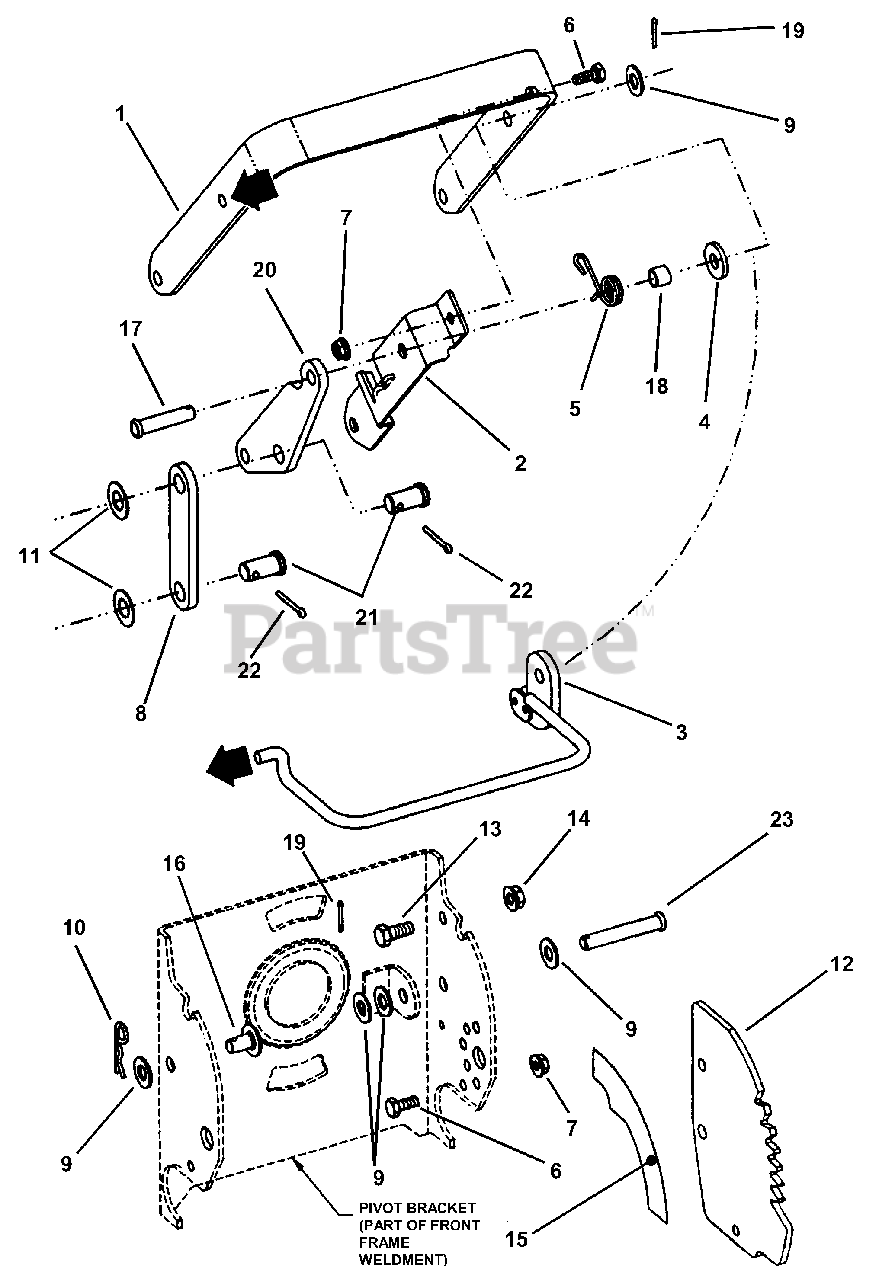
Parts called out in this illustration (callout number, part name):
1	HANDLE, Deck Lift
2	BRACKET, Pivot Support
3	WELDMENT, Deck Lift Handle
4	WASHER, Slipper
5	SPRING, Torsion (Deck Position)
6	SCREW, 1/4-20 x 5/8" Hex Head Cap, Grade 5
7	NUT, 1/4-20 Hex Flange Lock
8	LINK, Connector
9	WASHER, 3/8" Flat
10	HAIRPIN, 3/32 x 1-1/2"
11	WASHER, 1/2" SAE Flat
12	DETENT, Lift Handle
13	SCREW, 5/16-18 x 3/4" Hex Cap, Grade 5
14	NUT, 5/16-18 Hex Flange Lock, Grade 5
15	DECAL, Deck Position
16	PIN, 3/8 x 1/2" Expanded Head Clevis
17	PIN, 3/8 x 1-5/8" Clevis
19	PIN, 3/32" x 3/4" Cotter
20	PLATE, Connector Arm
21	PIN, 1/2 x .725 Clevis
22	PIN, 1/8 x 1" Clevis
23	PIN, Clevis, 3/8 x 2.00
